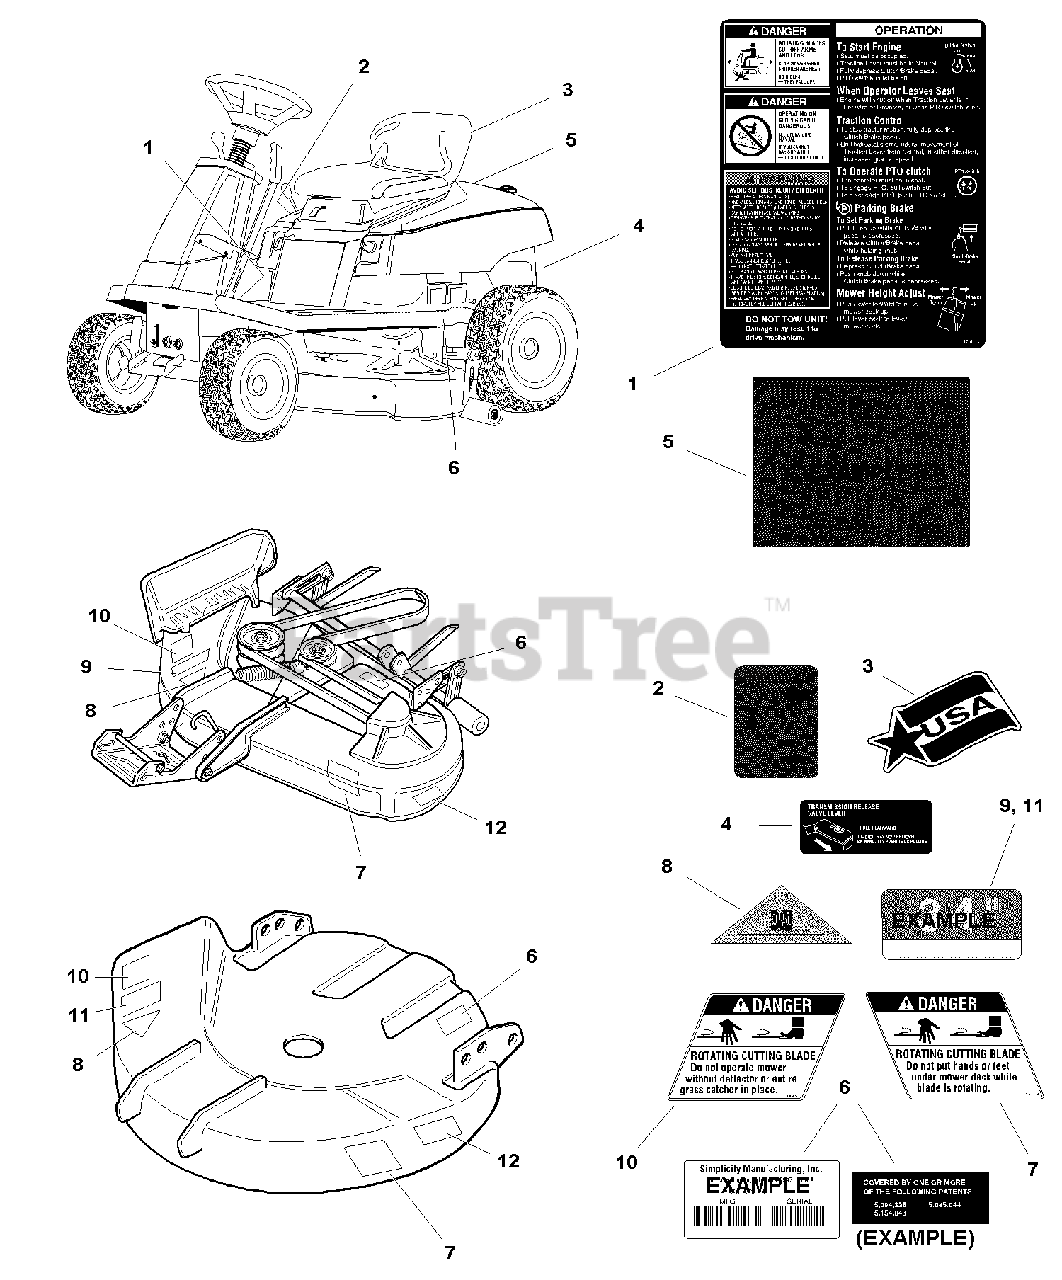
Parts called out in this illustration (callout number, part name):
1	DECAL, Operating Instructions
2	DECAL,Throttle/Choke
2	DECAL,Throttle/Choke (Red)
3	DECAL, USA (Seat Back)
4	DECAL, Transmission Release (Hydro models only)
5	DECAL, Belt & Blade Replacement
6	I.D. PLATE (Not Serviced)
7	DECAL, Danger, Rotating Cutting Blade
8	DECAL, OPEI, (Not Serviced)
9	DECAL, Cutting Width - 34", Black, Blue & Gray
9	DECAL, Cutting Width - 34", Silver on Black
10	DECAL, Danger, Chute In Place
11	DECAL, Cutting Width - 30", Black, Blue & Gray
11	DECAL, Cutting Width - 30", Silver on Black
12	DECAL, Free Floating Mower
